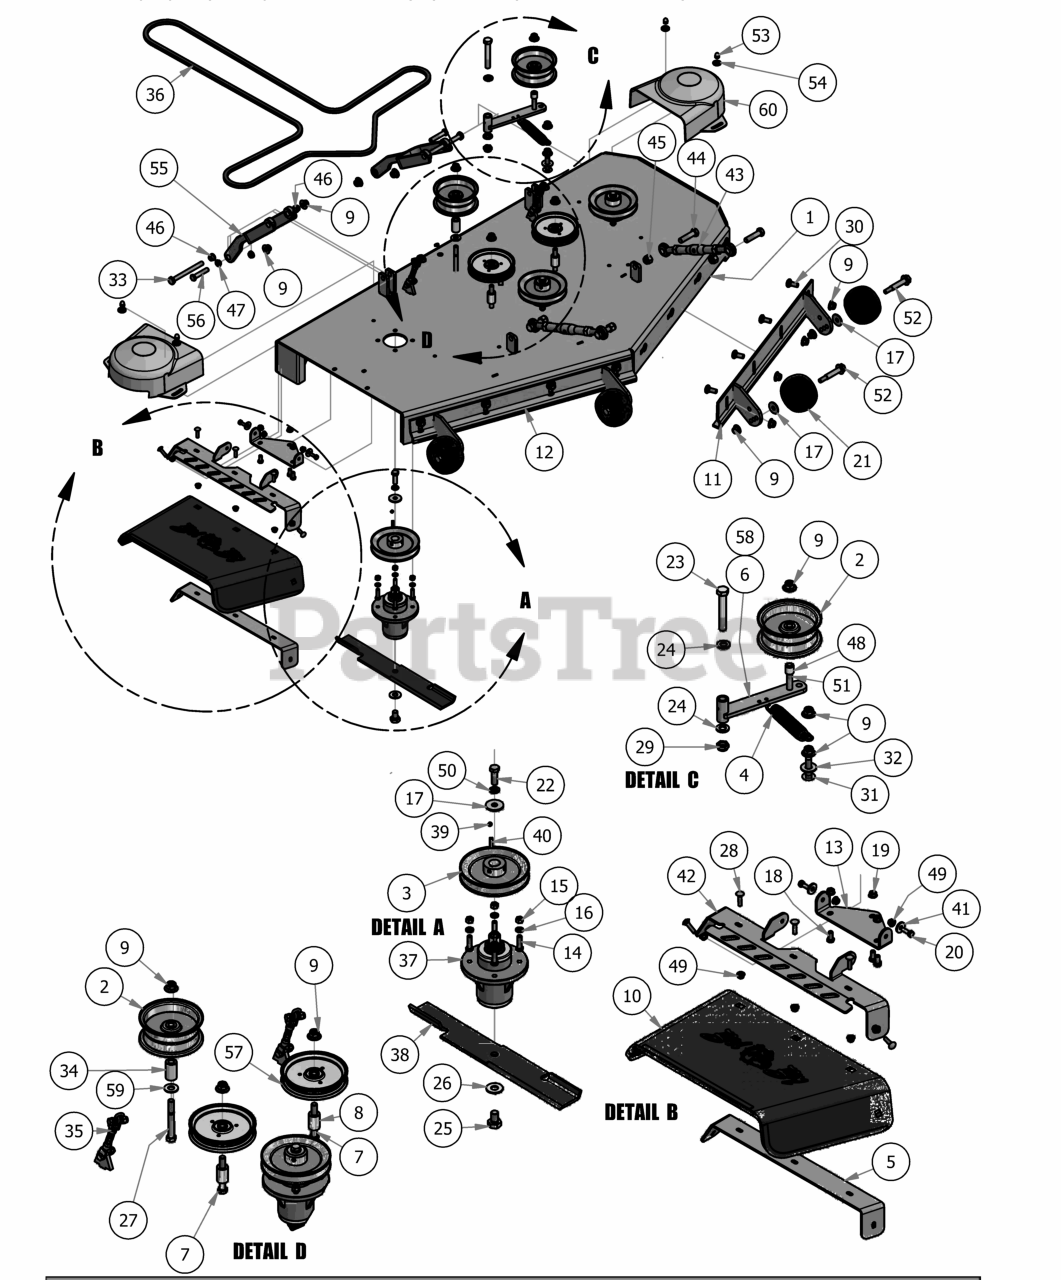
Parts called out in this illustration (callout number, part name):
1	61" AOS Deck
2	5 3/4" Deck Idler Pulley
3	6 1/4" Drive Pulley
4	Deck Idler Spring
5	60" Discharge Lower Bracket
6	Deck Idler
7	1/2 x 3 1/2 Flange Bolt Grade 8
8	Idler Pulley Standoff
9	1/2-13 Nylon Insert Flange Nut
10	Rubber Discharge Chute
11	61 Outlaw Adjustable Deck Front (Left)
12	61 Outlaw Adjustable Deck Front (Right)
13	Discharge Chute Hanger (deck mounted)
14	3/8" x 1 1/4" Hex Bolt
15	3/8-16 Hex Nuts Zinc
16	3/8 Lockwasher Zinc
17	1/2" Belleville Washer
18	3/8" x 3/4" Hex Bolt
19	3/8" Flange Nut
20	5/16" x 1" Bolt
21	Anti-Scalp Roller
22	1/2"-20 x 1 1/2 - Grade 5 Fine Thread Bolt
23	5/8" x 4" Hex Bolt
24	.630 ID Plastic Washer
25	5/8" x 1 1/2" Grade 8 Hex Bolt (Fine)
26	5/8'' Flat Washer
27	1/2" x 4" Bolt (Grade 8)
28	5/16" x 1 1/4" Carriage Bolt
29	5/8-11 Nylon Insert Jam Half Nut
30	1/2" x 1 1/4 Carriage Bolt
31	1/2 x 2" Carriage Bolt
32	.517 Square Hole Round Washer
33	1/2" x 5 1/2" Bolt
34	1 3/4" Pulley Spacer
35	4 - Link Adjustable Deck Hange
36	B236 Belt - Diesel EZ Ride
37	Double Bearing Spindle
38	61 inch Fusion Blade
39	5/16 Set Screw
40	1/4" x 1" Key
41	.360 ID Plastic Washer
42	60" Discharge Chute Upper Hanger
43	Turnbuckle (Top Link)
44	5/8" x 2 1/2" Grade 5 Hex Bolt (Coarse)
45	5/8 Std NC Nylock Nut
46	Flange Bushing For Upper Deck Arm
47	Flange Bushing For Lower Deck Arm
48	Spacer 3/4 OD x 1/2 ID x 3\4 Length
49	5/16" Nylon Flange Nut
50	1/2" Lock Washer
51	1/2-13 x GR 5 Hex Bolt Zinc
52	Deck Wheel Bolt
53	Acorn nut-pulley Cover
54	.360 ID Plastic Washer-Black
55	Deck Arm Assembly
56	1/2" x 3" Hex Bolt
57	5-3/4 Idler Pulley-Capitol Stampings
58	Deck Idler Assembly-parts of Assembly 2,6,9,49,52
59	1/2" Washer (Grade 8)
60	2014 ZT Pulley Cover
